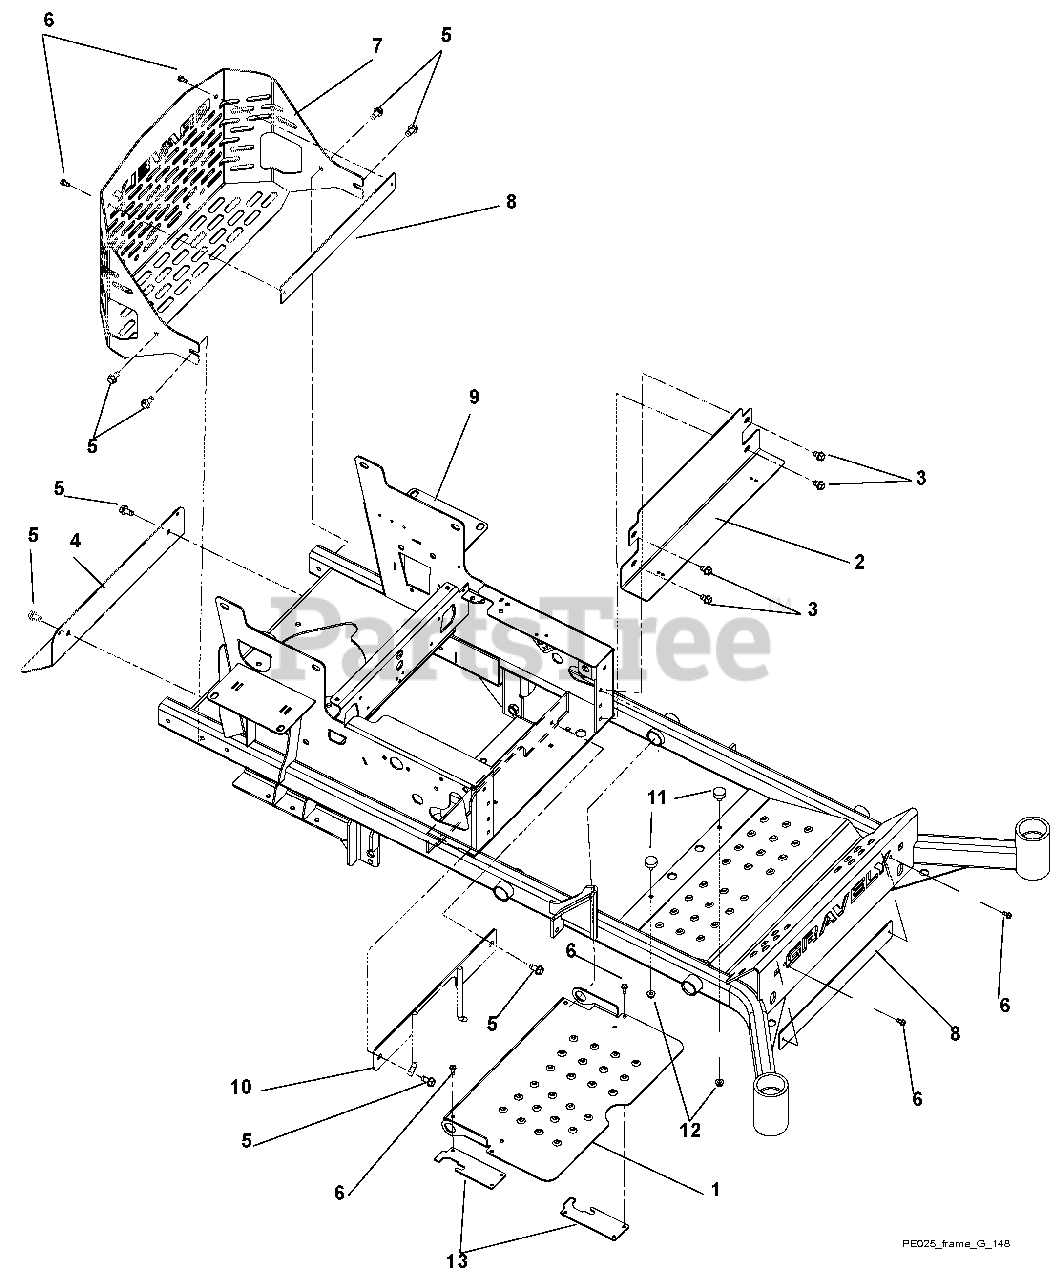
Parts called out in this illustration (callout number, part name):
1	Foot Plate
2	Kick Plate
3	Screw, Tapping .38-16 x .50 Hex Washer Head Thread Rolling
4	Muffler Heat Shield
5	Screw, Tapping .38-16 x .75 Hex Washer Head
6	Screw, Tapping .25-20 x .50 Hex Washer Head
7	Pro-Turn 100 Bumper
8	Bumper Plate
9	Frame, Pro-Turn 100 48"
10	PTO Belt Finger Weldment
11	Bumper, Rubber
12	Nut, Spin Lock-Flange .312-18
13	Pro-Turn 100CE Foot Plate Finger Cover
